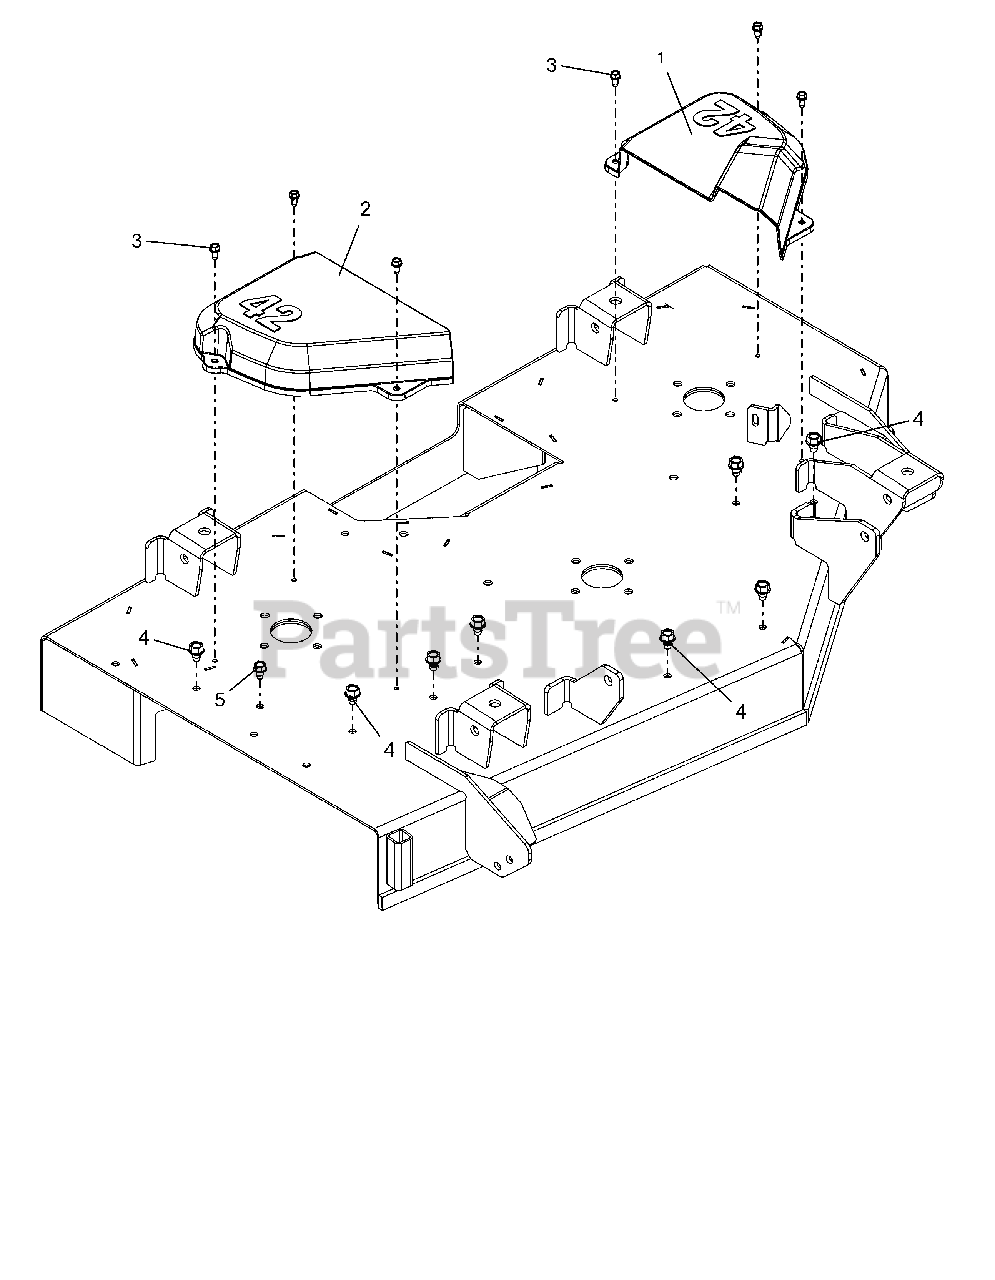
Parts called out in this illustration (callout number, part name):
1	COVER, BELT 42" LH
2	COVER, BELT 42" RH
3	SCR-TAP .25-20X.50 HWH ZCC
4	SCR,TAP .375-16X.50 HWH TR ZCC
5	@SCR-TAP .31-18X.50 HWH TR YWZ
